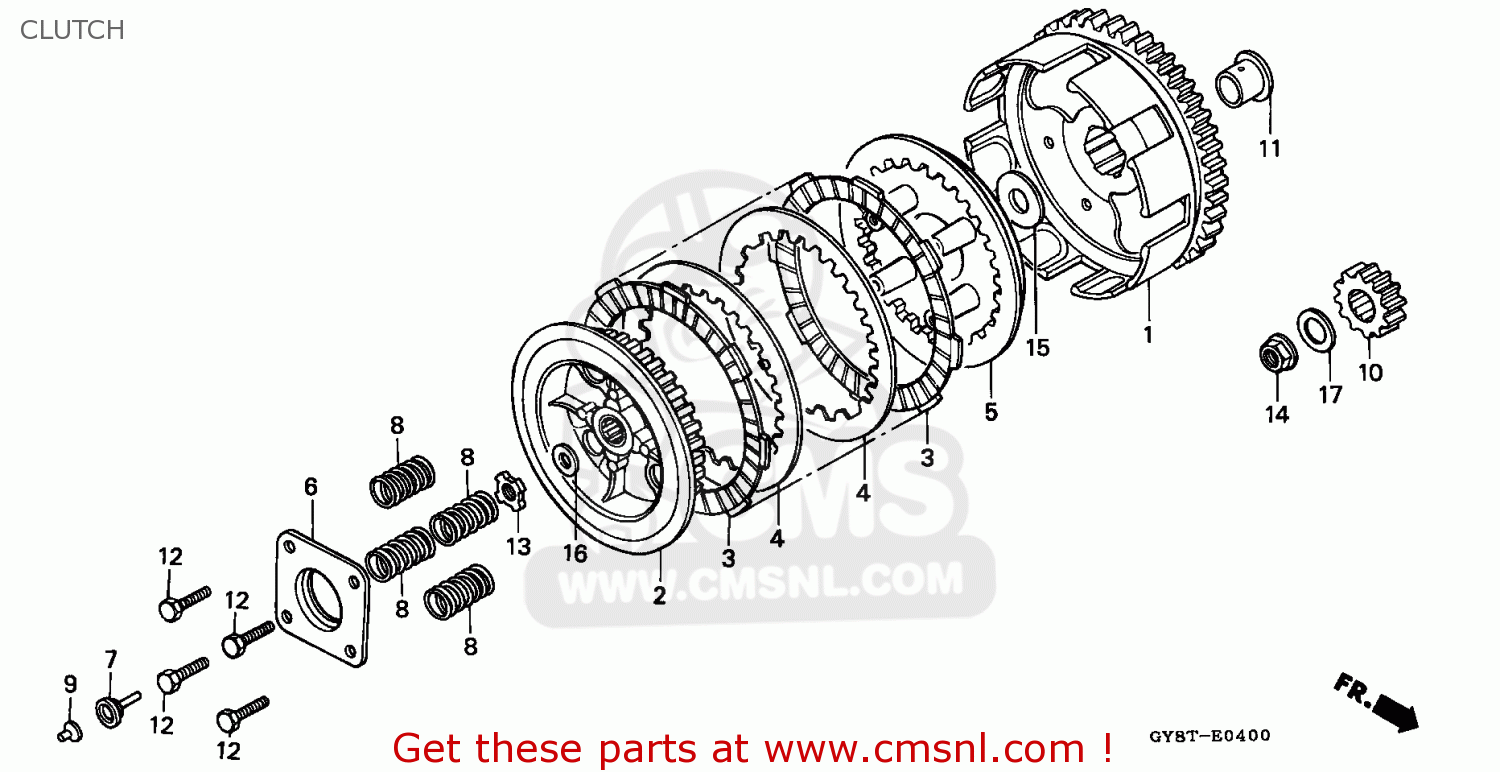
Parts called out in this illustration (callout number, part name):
1	OUTER COMP.,CLUTC
2	CENTER,CLUTCH
3	DISK,CLUTCH FRICT (NAS)
4	PLATE,CLUTCH
5	PLATE,PRESSURE
6	PLATE,CLUTCH LIFT
7	ROD ASSY.,CLUTCH
8	SPRING,CLUTCH
9	PIN,CLUTCH LIFTER
10	GEAR,RRIMARY (17)
11	COLLAR 17X30.6
12	BOLT,HEX.6X25
13	NUT,LOCK,14MM
14	NUT, LOCK, 12MM
15	WASHER,PLAIN,17MM
16	WASH B THRUST 14
17	WASHER,PLAIN,12MM
